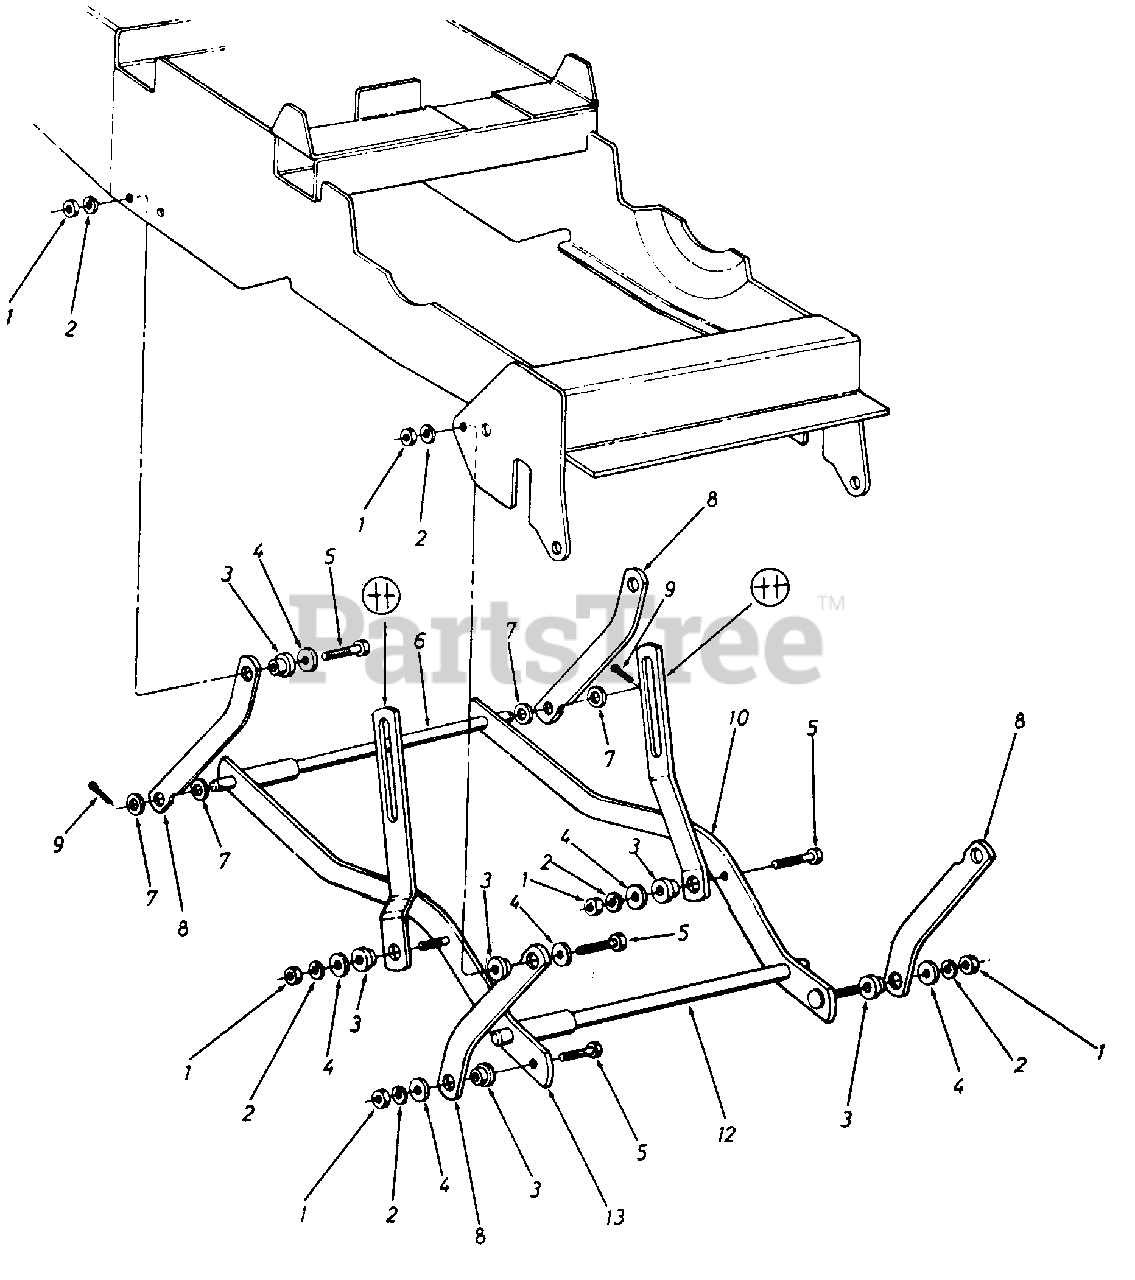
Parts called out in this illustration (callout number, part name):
1	Hex Nut 3/8-24 Thd.
2	L.-Wash. 3/8" Scr. Heavy Duty
3	Shoulder Spacer
4	Fl.-Wash. 3/8"1.D. x 1.0" O.D.
5	Hex Scr. 3/8-24 x 1.50" Lg. Grade 5
6	Cross Shaft Ass'y.-Rear
7	Fl.-Wash. 5/8" I.D. x 1-1/8"0.D.
8	Lift Arm
9	Cotter Pin 5/32" Dia. x l.25"Lg.
10	LiftArm Link Ass'y.-L.H.
12	Cross Shaft Ass'y. Front
13	Lift Arm Link Ass'y.-R.H.
